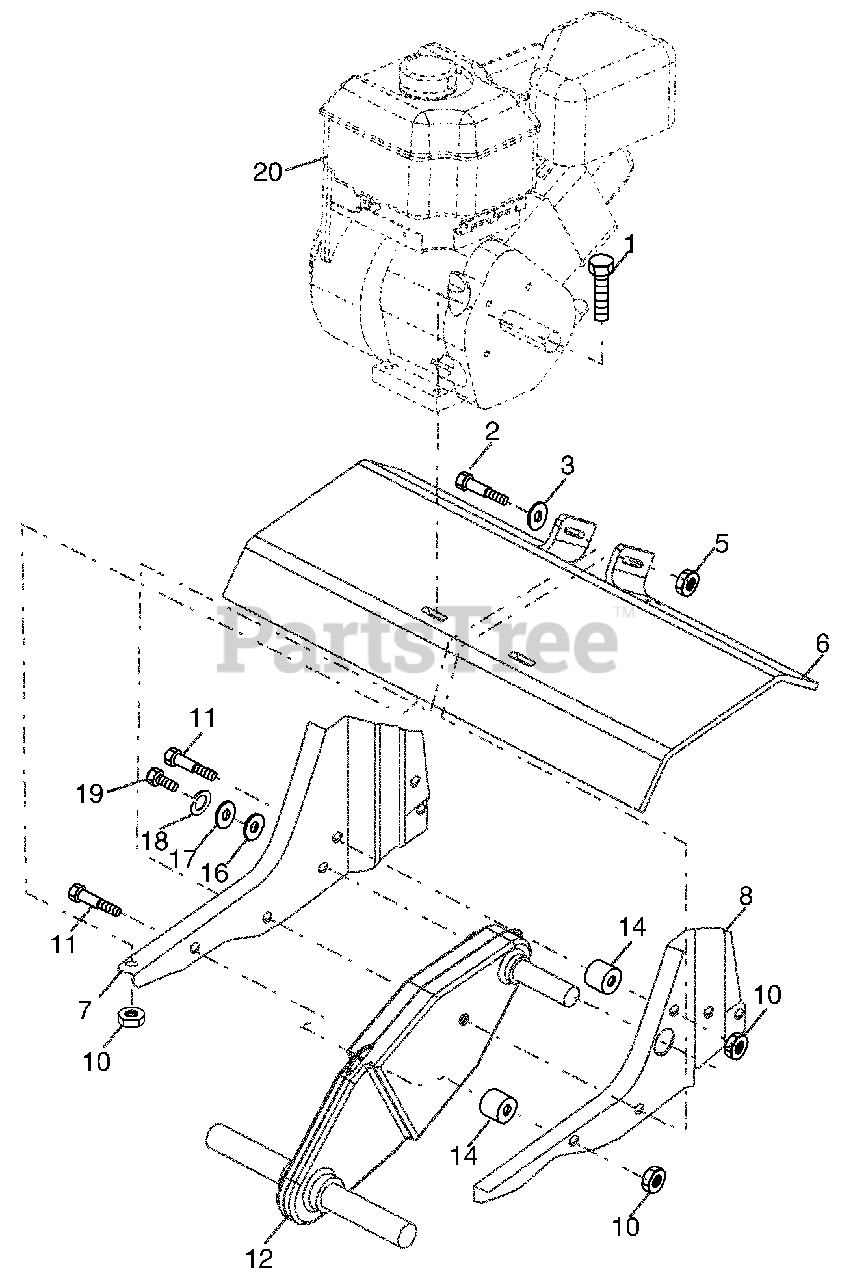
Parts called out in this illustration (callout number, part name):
1	Bolt, Hex 5/16-18 x 1-1/2 Gr. 2
2	Bolt, Hex, Fin 3/8-16 x 3-1/4
3	Washer 13/32 x 13/16 x 11
5	Nut Lock Flg 3/8-16 unc
6	Shield, Tine
7	Bracket, Engine, R.H.
8	Bracket, Engine, L.H.
10	Nut Lock Hex Flg
11	Bolt, Shoulder
12	Transmission
14	Spacer, Split
16	Washer 9/32 x 7/8 x 12 Ga.
17	Washer 9/32 x 1-1/4 x 16 Ga.
18	Washer, Lock 1/4
19	Bolt, Hex 1/4-28 x 3/4 Gr. 5
